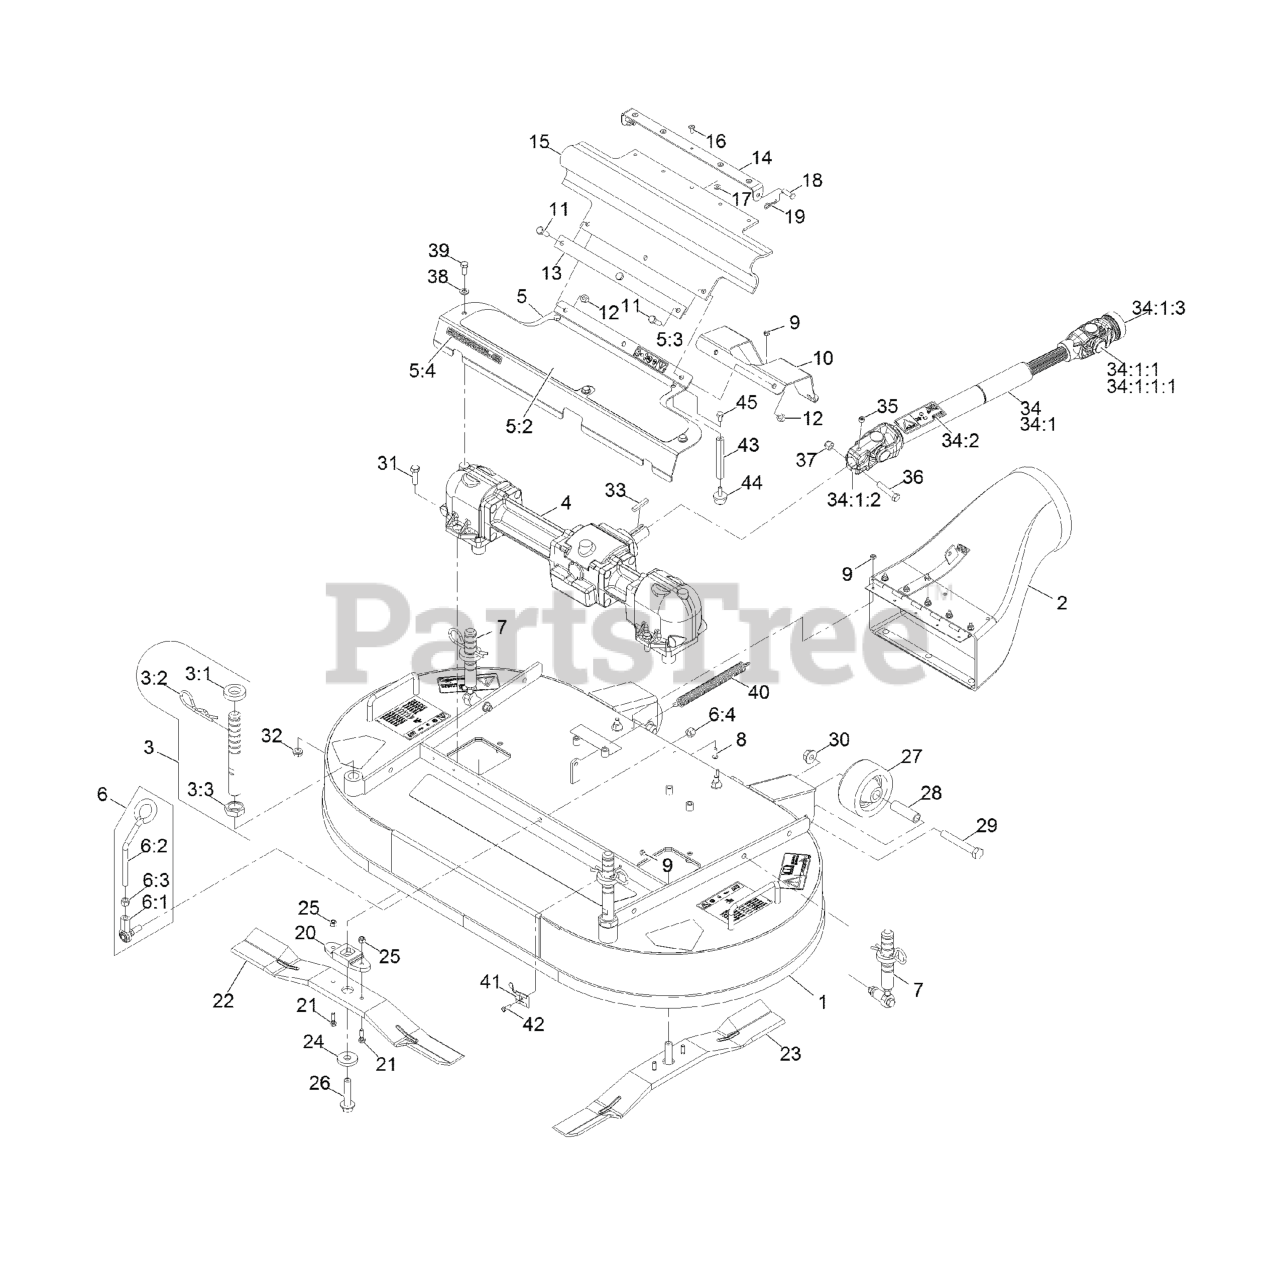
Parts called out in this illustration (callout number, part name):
1	DECK ASM
2	DISCHARGE TUBE ASM
3	FRONT DECK HEIGHT ADJUST
3:1	SPACER-DECK SUPPORT
3:2	PIN-CUT HEIGHT
3:3	NUT-JAM
4	GEARBOX ASM
5	ASM,GEARBOX COVER 42 W/DECAL
5:2	PAD-ANTI SKID
5:3	DECAL-DANGER
5:4	Decal-Commercial 42
6	DECK LATCH ASM
6:1	BALLJOINT-RH
6:2	LATCH-DECK
6:3	NUT-HEX
6:4	NUT-LOCK
7	REAR DECK HEIGHT ADJUST A
8	SCREW-HEAD, TRUSS
9	NUT-LOCK, NI
10	GUARD-DRIVE SHAFT
11	SCREW-HH
12	NUT-LOCK, NI
13	STRAP-DRIVE, LINE COVER
14	BRACKET-GUARD, PTO
15	GUARD-PTO
16	RIVET-BLIND
17	WASHER-FLAT
18	PIN-CLEVIS
19	PIN-COTTER
20	DRIVER-BLADE
21	BOLT-SHEAR
22	BLADE,22 INCH RH
23	BLADE,22 INCH LH
25	NUT-LOCK, NI
26	BOLT-BLADE
27	ROLLER-DECK
28	SPACER-ROLLER
29	SCREW-HH
30	NUT-HHF
31	SCREW-HH
32	NUT-HHF, WHIZ
33	KEY-SQUARE
34	DRIVE SHAFT ASM
34:1	Drive Shaft-Telescoping
34:1:1	U-JOINT KIT
34:1:1:1	FITTING-GREASE
34:1:2	YOKE-KEYED
34:1:3	YOKE-QUICK DISCONNECT
34:2	DECAL-DANGER, DRIVELINE
35	SCREW-SET, HSH
36	SCREW-HH
37	NUT-LOCK, NI
38	WASHER-PLAIN
39	SCREW-HH
40	SPRING-EXTENSION
41	CLIP-DECK, HOLD UP ROD
43	STAND-OFF
45	SCREW-HH
